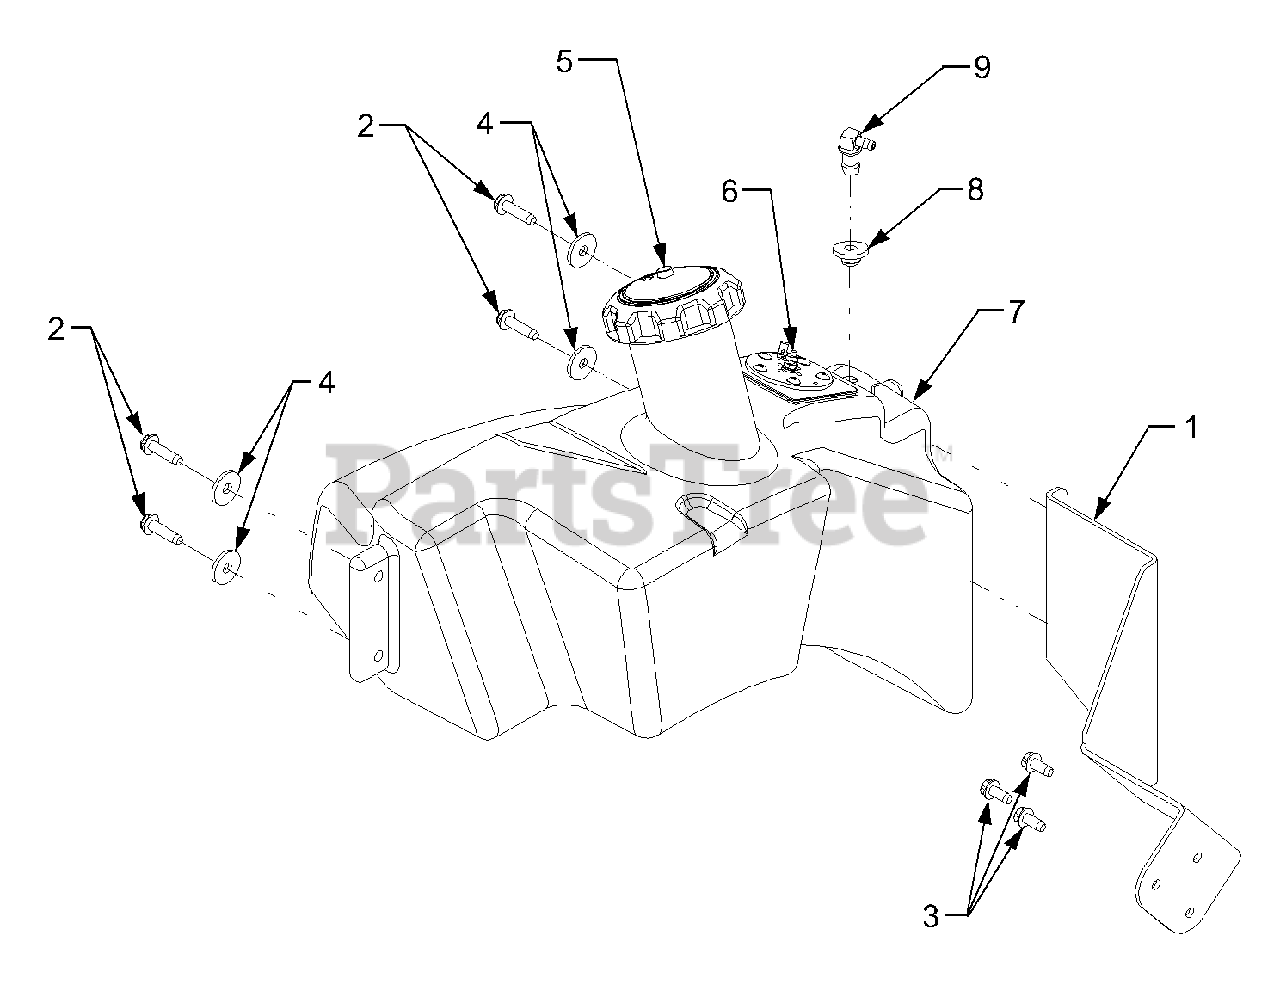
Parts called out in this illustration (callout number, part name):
1	Bracket, Front Tank Mtg.
2	Screw, Hex Wash Hd Tapp 5/16-18 x 1.25
3	Screw, Hex Wash Hd Tapp 5/16-18 x .75
4	Washer, Flat, .344 x 1.125 x .12
5	Cap, Fuel - Diesel
6	Sensor, Fuel Level
7	Tank, Fuel
8	Bushing, Rubber
9	Fitting, Fuel Return
